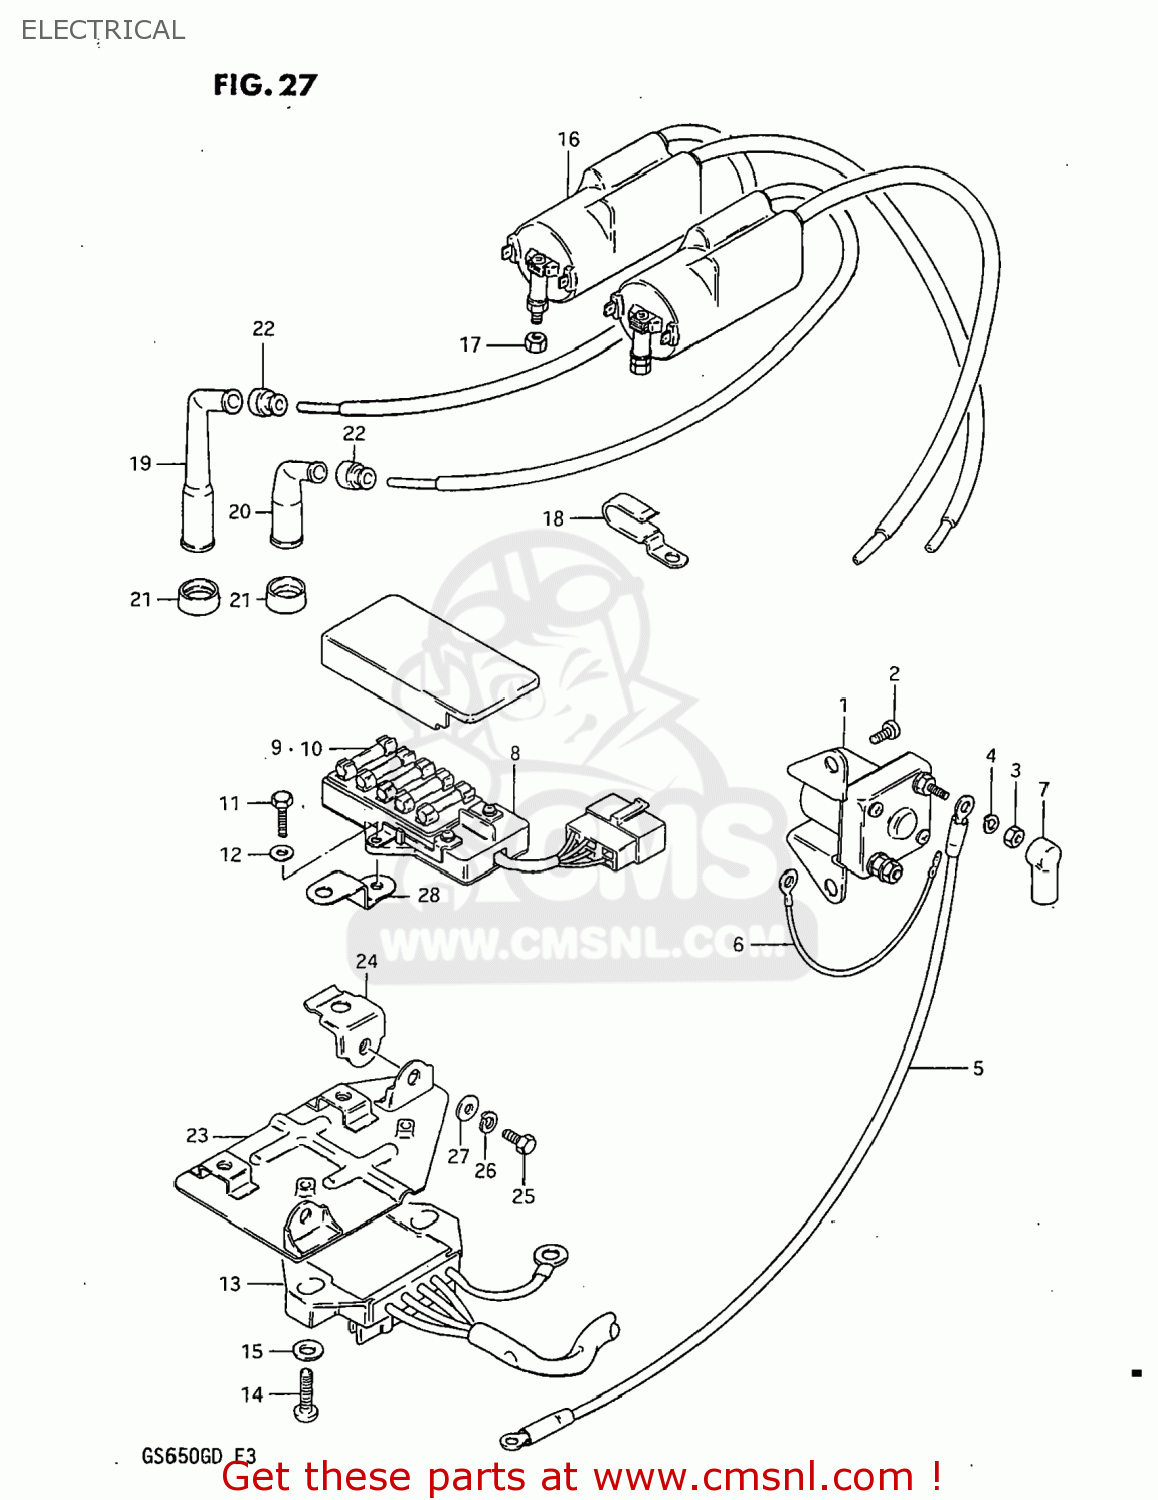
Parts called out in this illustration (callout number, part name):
1	RELAY ASSY,STARTING MOTOR
2	SCREW
3	NUT 6MM
4	LOCK WASHER
5	CABLE,STARTING MOTOR
6	LEAD WIRE
7	CAP,STARTER RELAY
8	BOX ASSEMBLY,FUSE
9	FUSE(15A)
10	FUSE(10A)
11	BOLT, UPPER
12	WASHER
13	RECTIFIER ASSEMBLY
14	SCREW 6X12
15	WASHER
16	COIL ASSEMBLY,IGNITION
17	NUT
18	CLAMP
19	CAP ASSY,SPARK PLUG
20	CAP,SPARK PLUG
21	SEAL,SPARK PLUG
22	SEAL,SPARK PLU
23	PLATE,ELECTRIC PARTS H
24	BRACKET, PARTS HOLDER
25	BOLT
26	LOCK WASHER
27	WASHER
28	BRACKET
